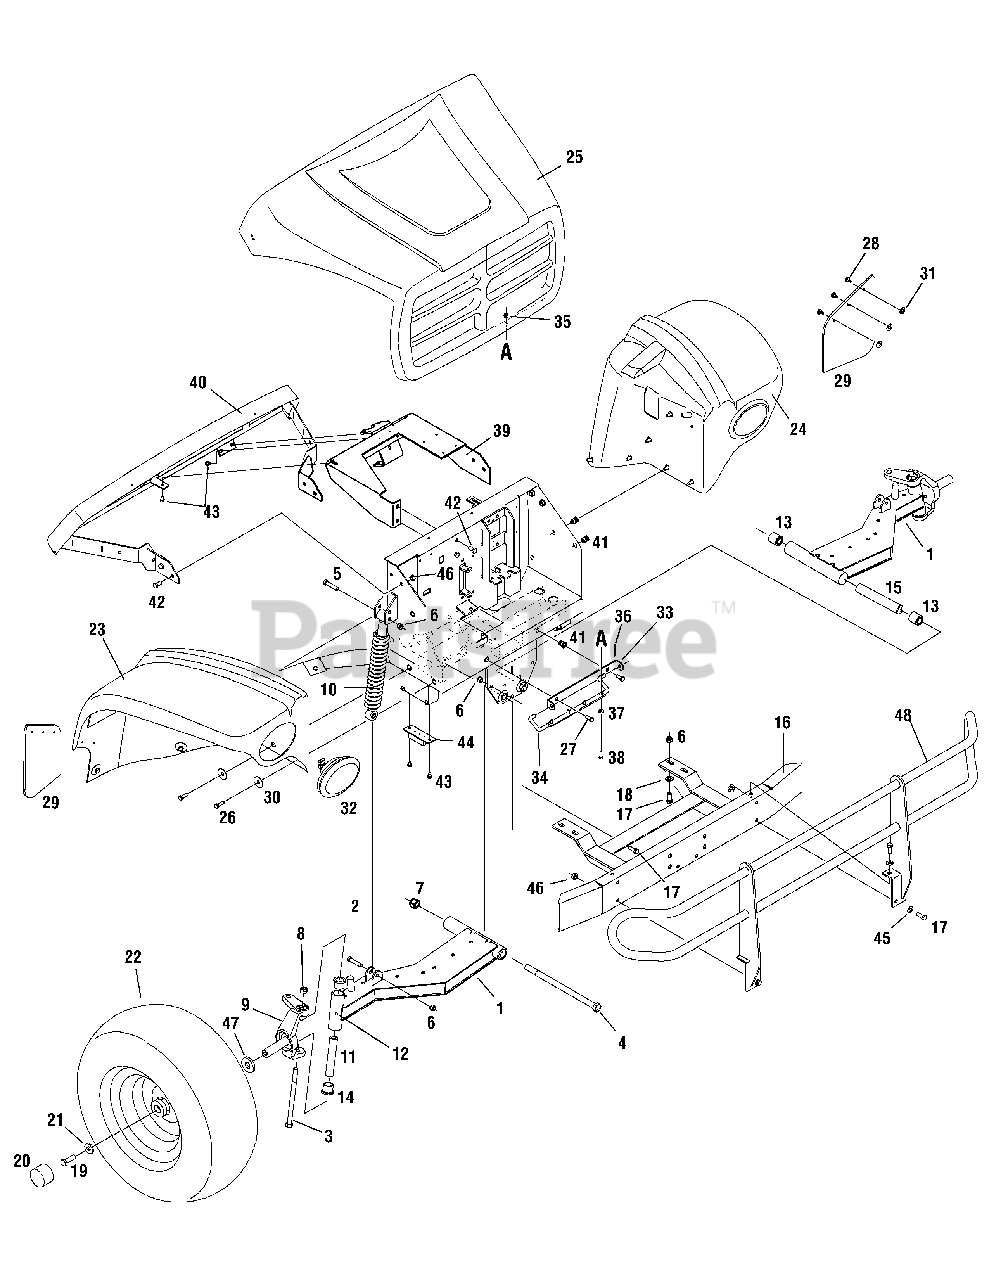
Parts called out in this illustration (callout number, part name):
1	Axle Assembly, Right-front
1	Axle Assembly, Left-front
2	Hex Screw, 3/8-16 x 1.75
3	Hex Screw, 1/2-13 x 7.0, Gr5
4	Hex Screw, 5/8-11 x 11.13, Gr5
5	Hex Screw, 3/8-16 x 2.25
6	Nut, Hex Lock, Nylon, 3/8-16, Gr5
7	Nut, Hex Lock, Nylon, 5/8-11, Gr5
8	Nut, Hex Lock, 1/2-13
10	Shock Absorber, 2.9 Stroke
11	Tube, .875 x .50 x 4.75
12	Grease Fitting
13	Bearing, .63 ID x 1.19 OD
14	Bushing, Steering
15	Spacer, .645 ID x 1.063 OD
18	Flat Washer, .406 x .875 x .059
19	Hex Screw, 1/2-13 x 1.25, Gr5
21	Flat Washer, .531 x 1.25 x .181
22	RH Wheel Assembly, 22 x 11 x 10
22	LH Wheel Assembly, 22 x 11 x 10
23	Panel Ass’y, Right Fender, Camo
24	Panel Ass’y, Left Fender, Camo
25	Panel Ass’y, Hood, Camo
26	Hex Screw 5/16-18 x 1.00 Gr 5
27	Hex Screw, 5/16-18 x .75
28	Rivet, Pop
30	Washer, Bell, .39 x 1.38 x .062
31	Flat Washer, .194 x .62 x .063
32	Headlamp Assembly
35	Nut, Hex Lock, 1/4-20
36	Cotter Pin, Internal, 1.42
37	Washer, Flat, .271 x .63 x .065
38	Hex Screw, 1/4-20 x .75
41	Insert Nut, 5/16-18
42	Hex Screw, 3/8-16 x .75
43	Screw, Self-tapping, 1/4-20 x .5
44	Suspension Bumper
45	Washer, Flat, .406 x .812 x .051
46	Nut, Flange Lock, 3/8-16
47	Washer, Flat, 1.030 x 1.625 x .090
48	Brush Guard
